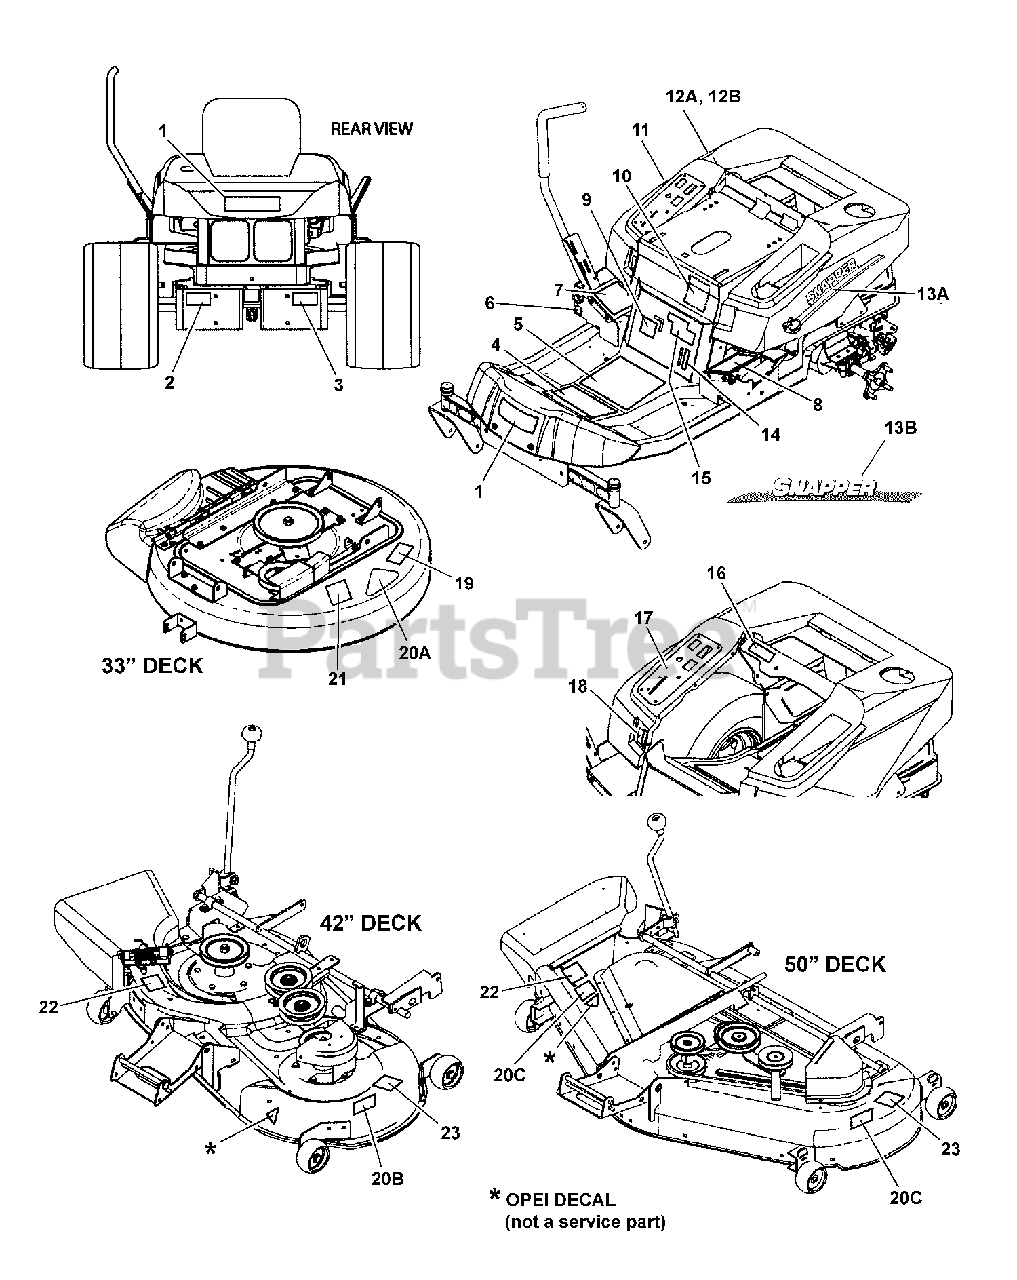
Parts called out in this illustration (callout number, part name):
1	DECAL, SNAPPER Logo
2	DECAL, Caution Cut Hazard
3	DECAL, Transmission Release ZTS Export
4	DECAL, Handles Operation
5	DECAL, Operator Instructions
5	DECAL, Operator Instructions (CE/Export)
6	DECAL, Tracking Adjustment ZT 7000
7	DECAL, RH Handle
8	DECAL, LH Handle Control ZTS 7500
9	DECAL, Parking Brake, ZT
10	DECAL, Belt/Blade 33" ZT
10	DECAL, Belt/Blade ZT
11	DECAL, Hot Surfaces
12A	DECAL, SNAPPER-RH Stripe & Logo ZT
12B	DECAL, New SNAPPER Stripe, RH
13A	DECAL, SNAPPER-LH Stripe & Logo ZT
13B	DECAL, New SNAPPER Stripe, LH
14	DECAL, Height-Of-Cut
14	DECAL, Height-Of-Cut, Without Best Cut (CE/Export)
15	DECAL, 150Z 18.5HP SNAPPER ZT
15	DECAL, 150Z 20HP SNAPPER ZT (CE/Export)
15	DECAL, 150Z 21HP SNAPPER ZT
15	DECAL, 150Z 26HP SNAPPER ZT
16	DECAL, Do Not Remove Foam Around Engine
17	DECAL, Instrument Panel ZTS 7500
17	DECAL, Instrument Panel (CE/Export)
17	DECAL, Instrument Panel ZTS 7600
18	DECAL, Mower Cutting Height ZTS 7500
19	DECAL, Danger Do Not Operate w/o Deflector
20A	DECAL, 33" Hi-Vac
20B	DECAL, 42" 2006 Silver/Black
20C	DECAL, 50" Silver on Black w/Stripe
21	DECAL, Warning/Danger
22	DECAL, Danger Do Not Operate w/o Deflector
23	DECAL, Danger Do Not Put Hands/Feet in Mower
